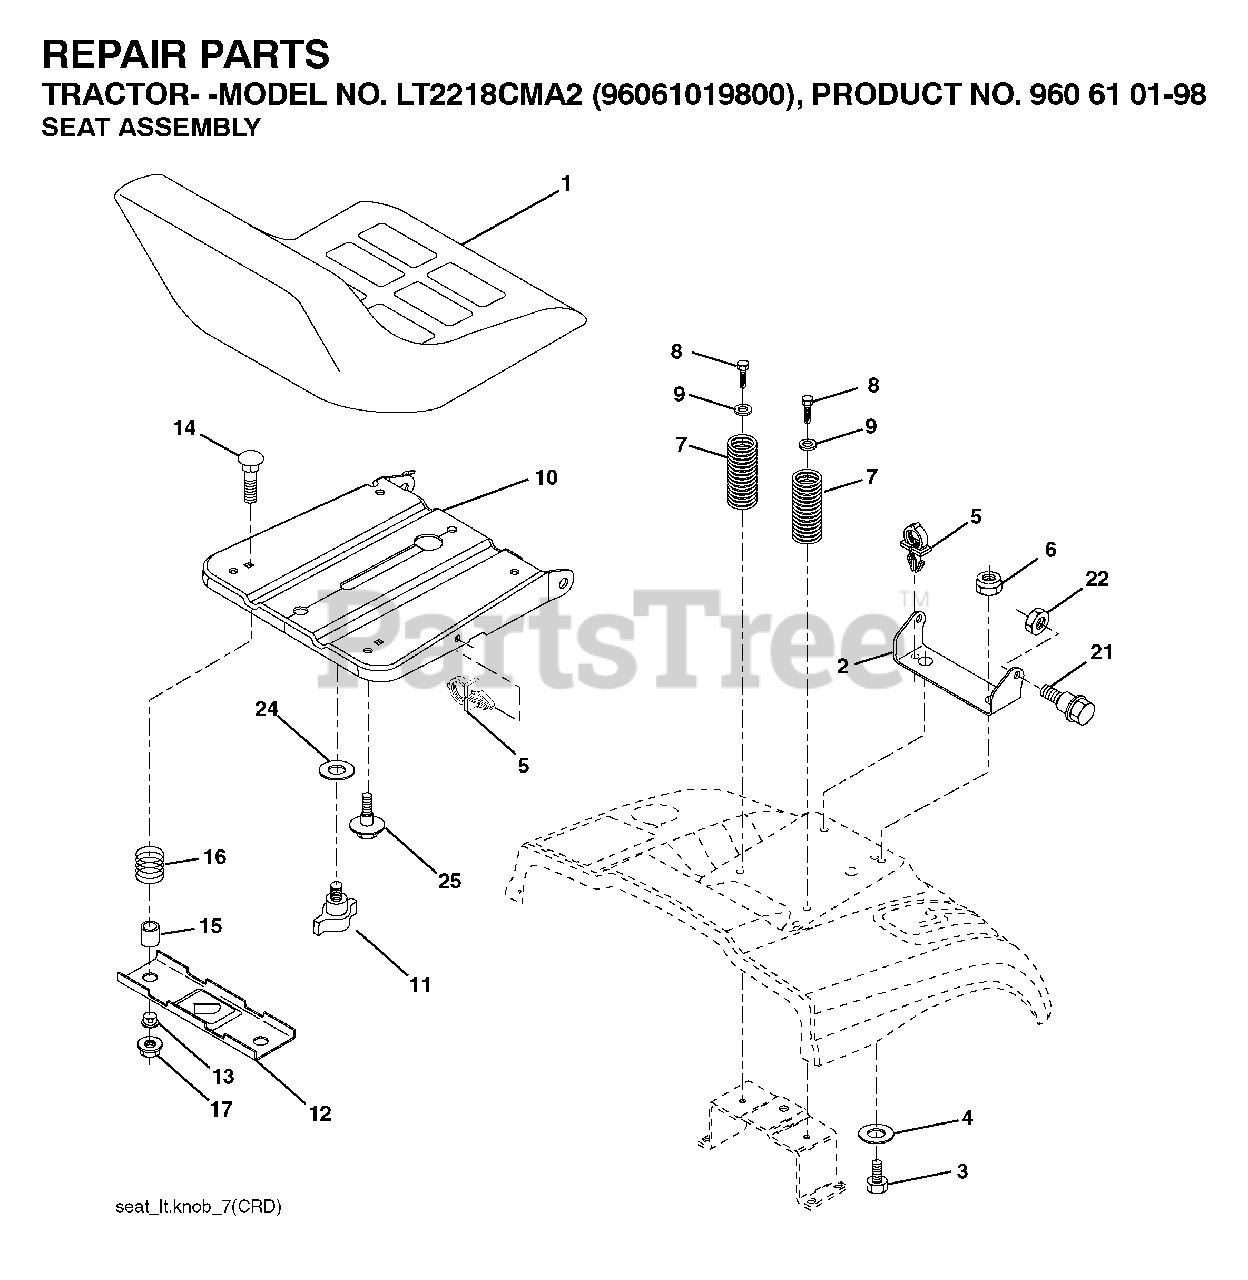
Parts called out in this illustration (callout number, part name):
1	SEAT.XG150.BLK.KB/SLD.NO-LOGO
2	SEAT PIVOT BRKT
4	WASHER PM
5	PUSH CLIP
6	NUT
7	SPRING COMPRESSION
8	SCREW 3/8-16X1
9	WASHER
10	PAN.ASM.SEAT.1SLOT
11	KNOB.SEAT.ADJ.WINGNUT
12	BRKT.MNTNG.SWITCH.SEAT
14	BOLT.ROUND.HEAD.SQUARE.NECK
15	SPACER SPLIT 28X.96
17	NUT T
21	BOLT.SHOULDER.5/16-18
22	NUT.71038.31-18.HEX.NYLOCK
25	BOLT,SHOULD
